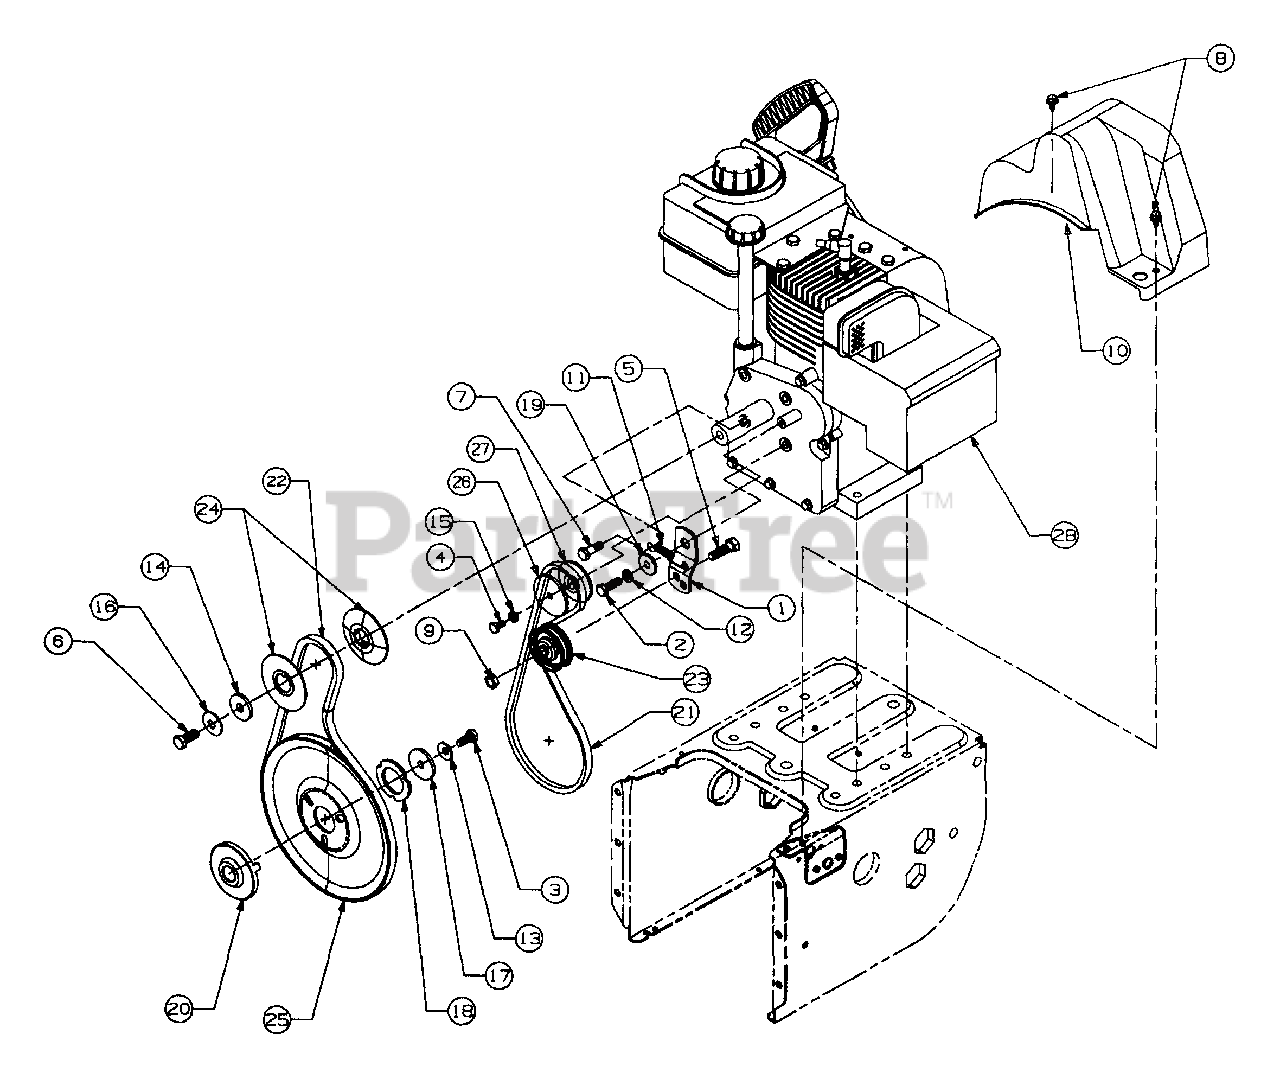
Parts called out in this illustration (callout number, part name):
3	Screw
4	Screw
5	Screw
6	Screw
7	Screw
8	Screw
9	Nut, Hex Jam
10	Belt Cover
11	Spring
12	Washer - Lock
13	Washer - Bell
14	Washer
15	Washer
16	Washer - Bell
17	Washer - Flat
18	Washer
19	Shoulder Spacer
20	Pulley, Adapter
21	V-Belt
22	V-Belt Matched
23	Idler, Flat
24	Pulley, Half
25	Pulley, Auger
26	Pulley, Half
27	Pulley, Half
28	Eng., HSSK Tec. 5.0 HP Horz.
